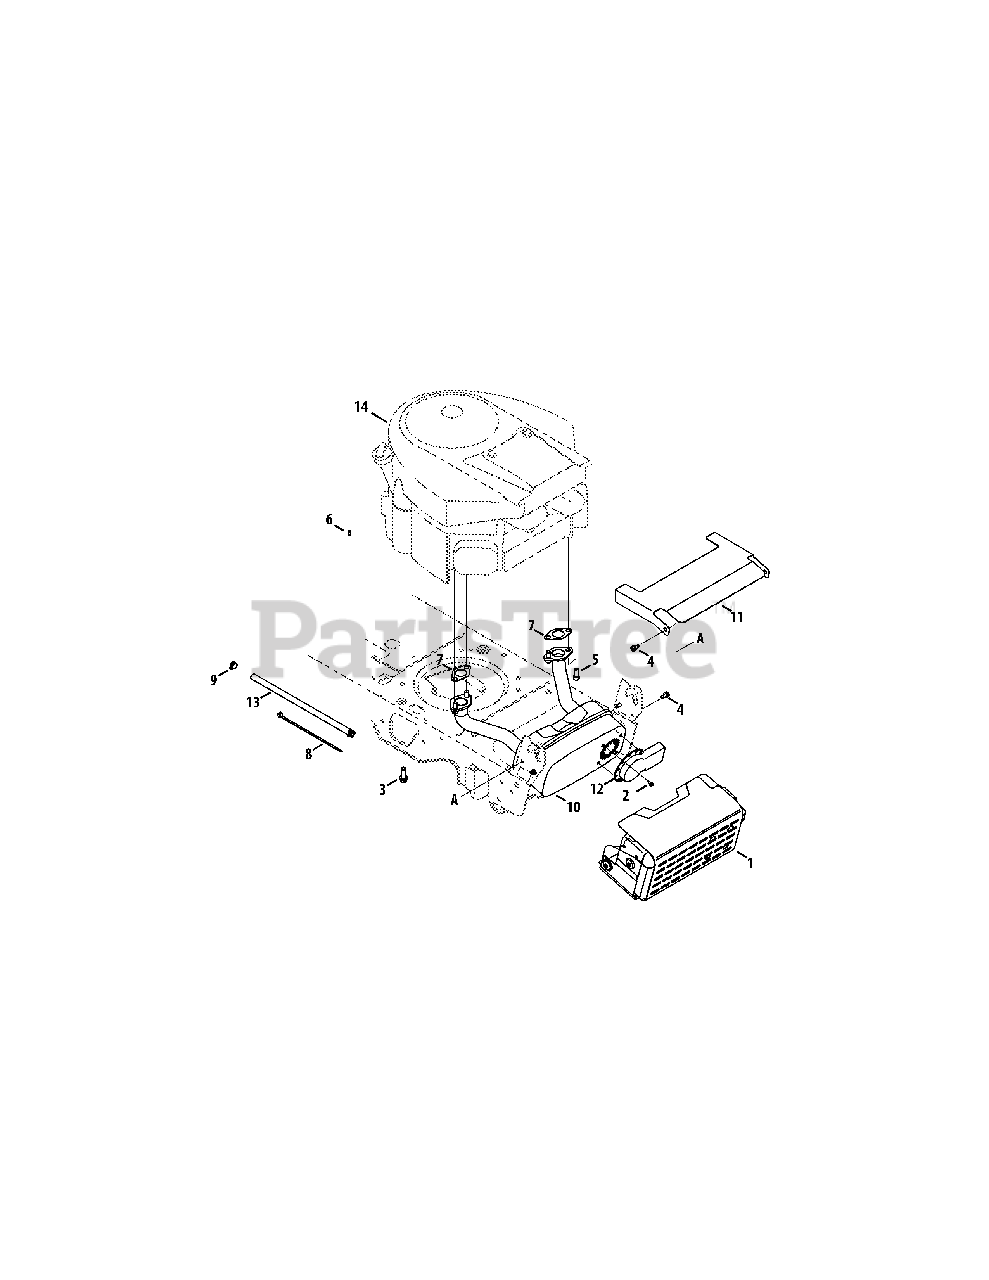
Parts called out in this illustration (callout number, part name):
1	Mulffler Shield Assembly
2	Screw, Indented Washer, #8-18:0.500
3	Taptite Screw, Indented Washer, 3/8-16:1.000
4	Taptite Screw, Indented Washer, 1/4-20:0.500
5	Socket Head Screw, 5/16-18:.750
6	Sems Nut, 1/4-20
7	Exhaust Gasket
8	Cable Tie, 3/16 x .05 x 7.4
9	Hose Clamp, .490 DIA.
10	Muffler
11	Heat Shield
12	Muffler Deflector
13	Fuel Hose
14	Replacement Engine 49M777-0853-G5
